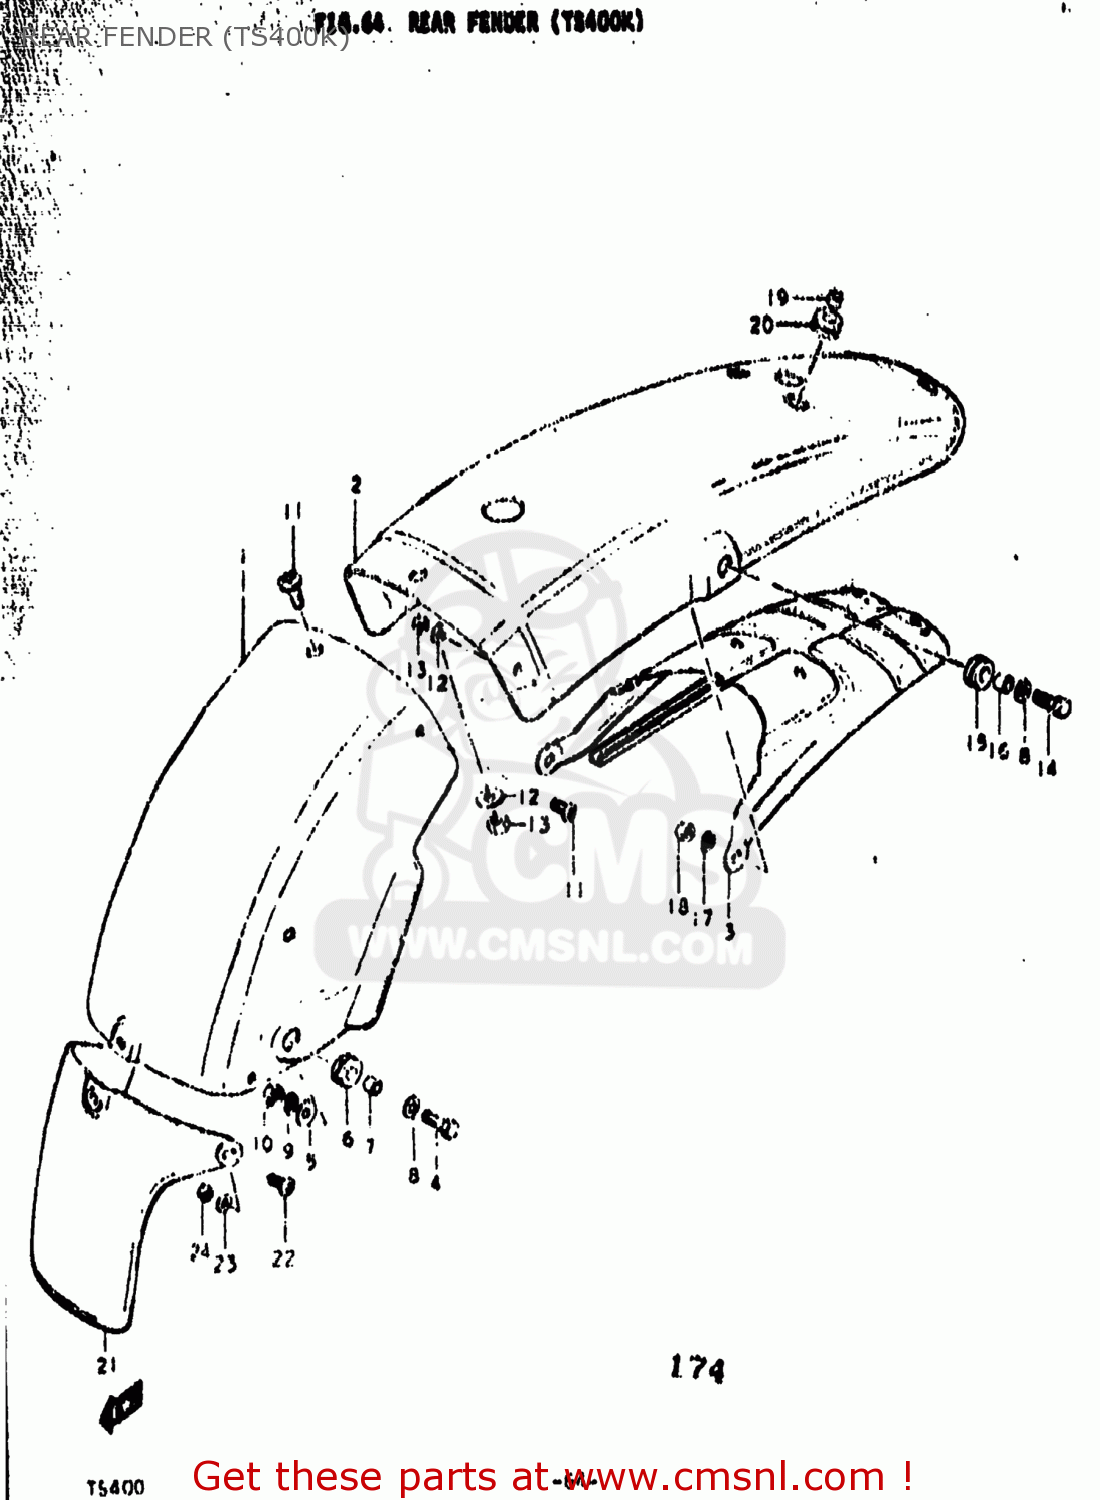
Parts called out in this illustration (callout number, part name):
1	FENDER,REAR
2	FENDER,REAR
3	REINFORCEMENT,REAR FENDER
4	BOLT
5	WASHER (6.5X20X1.2)
6	CUSHION
7	SPACER(6.1X9X7.5)
8	WASHER
9	LOCK WASHER
10	NUT
11	SCREW
12	WASHER
13	NUT
14	BOLT
15	CUSHION
16	SPACER(6.1X9X7.5)
17	LOCK WASHER
18	NUT
19	SPACER(6.1X9X7.5)
20	CUSHION
21	MUD GUARD,REAR FENDER
22	SCREW
23	WASHER
24	NUT
